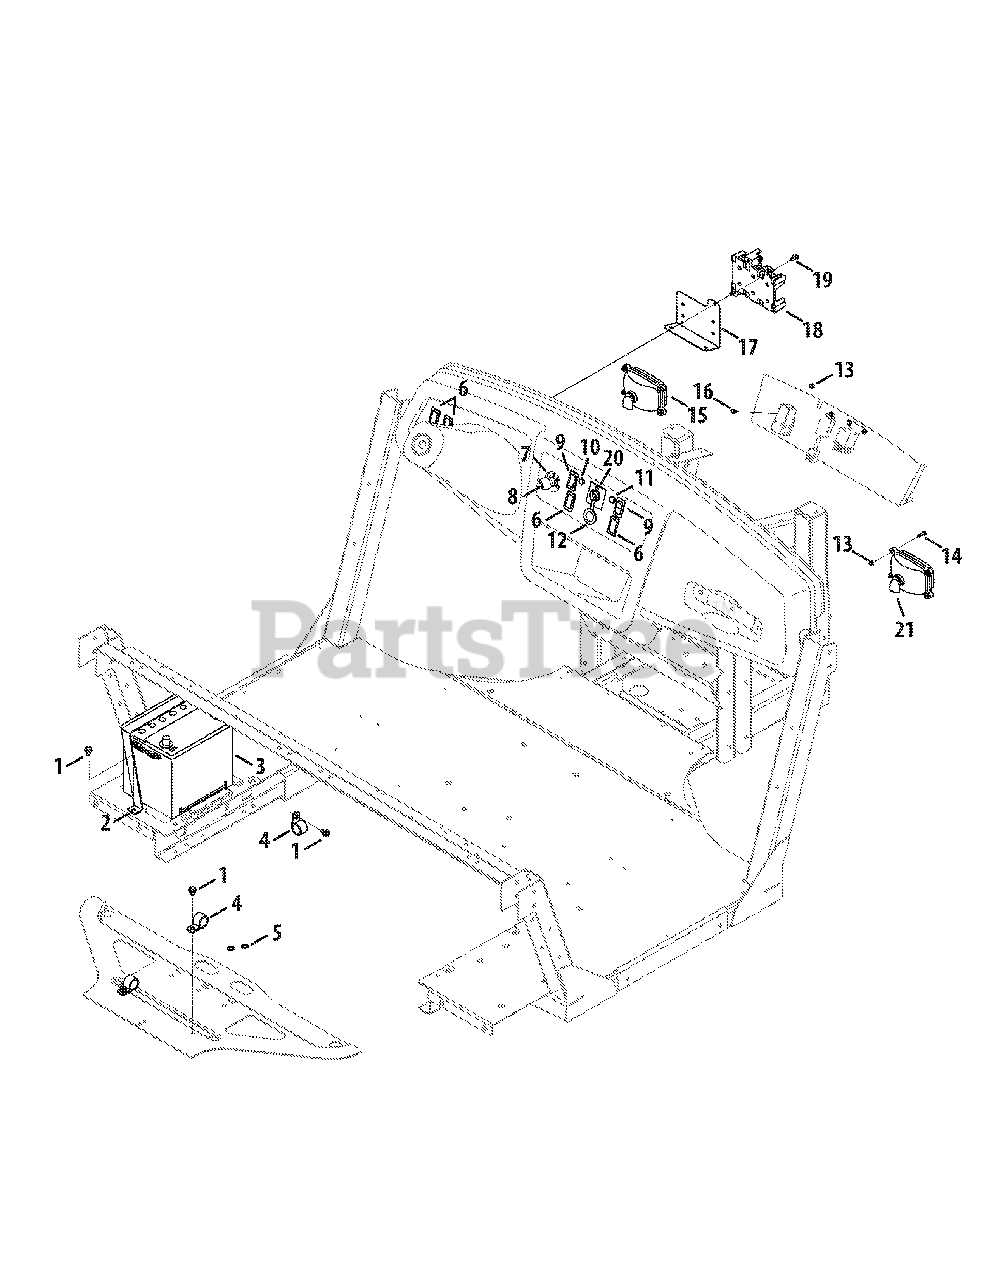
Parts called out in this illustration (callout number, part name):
1	Screw, TT, 5/16-18 x .500
2	Bracket, Mt., Battery
3	Battery, 450 CCA Wet
5	Washer, Lock, 5/16
6	Panel, Plug, Switch
7	Switch, Key, 4 Pos. Delta
8	Key, Delta, Plastic
9	Switch, 4x4, Rocker
10	Light, Ind., Yellow, LED
10	Lamp, Ind., Green, Incandescent
11	Light, Ind., Red, LED
11	Lamp, Ind., Red, Incandescent
12	Receptacle, Power, 12v
13	Nut, Hex Lock, #10-24
14	Screw, TT, #10-24 x .750
15	Headlight Assembly
16	Screw, #10-24 x .500
17	Bracket, Fuse Mount
18	Relay, Holder, 3-Way
19	Screw, TT, 1/4-20 x .500
20	Meter, Ind., Hour Flat Face
21	Head lamp Bulb
